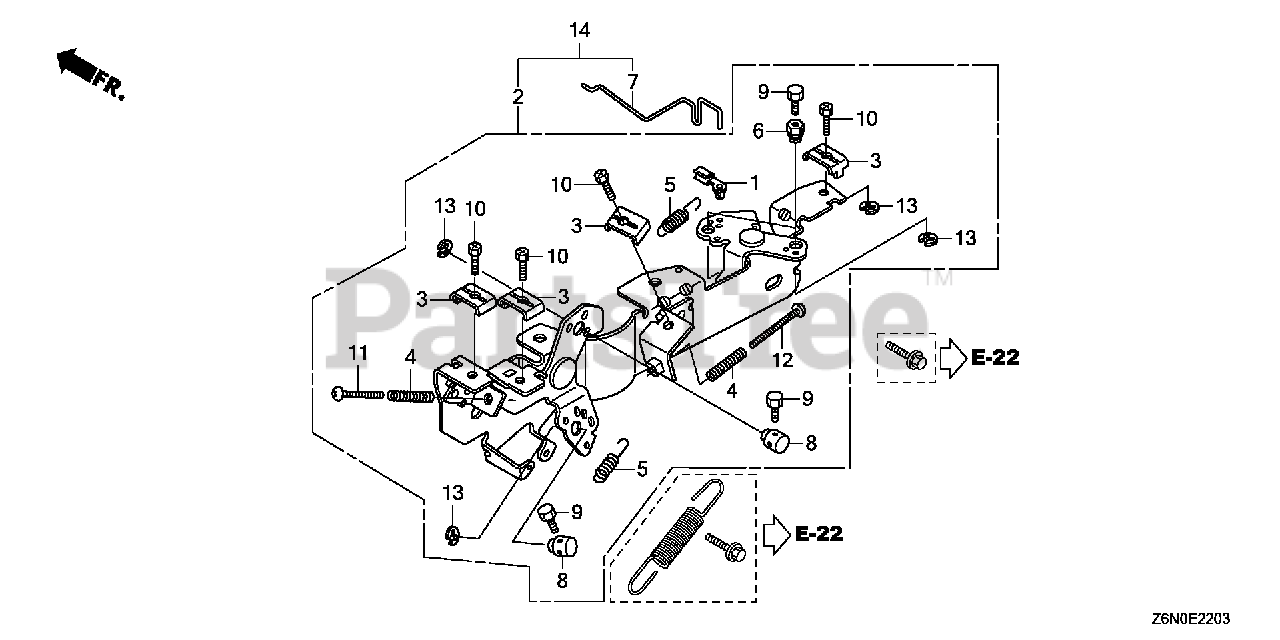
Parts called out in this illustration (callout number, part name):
1	JOINT, ROD
2	CONTROL ASSY.
3	HOLDER, CABLE
4	SPRING, CONTROL ADJUSTING
5	SPRING, CABLE RETURN
6	HOLDER, WIRE
7	ROD, CHOKE CONTROL
8	HOLDER, CABLE
9	BOLT, RECESSED (4X6)
10	BOLT, RECESSED (5X16)
11	SCREW, PAN (5X30)
12	SCREW, PAN (5X40)
12	SCREW, PAN (5X45)
13	E-RING (5MM)
14	CONTROL KIT
